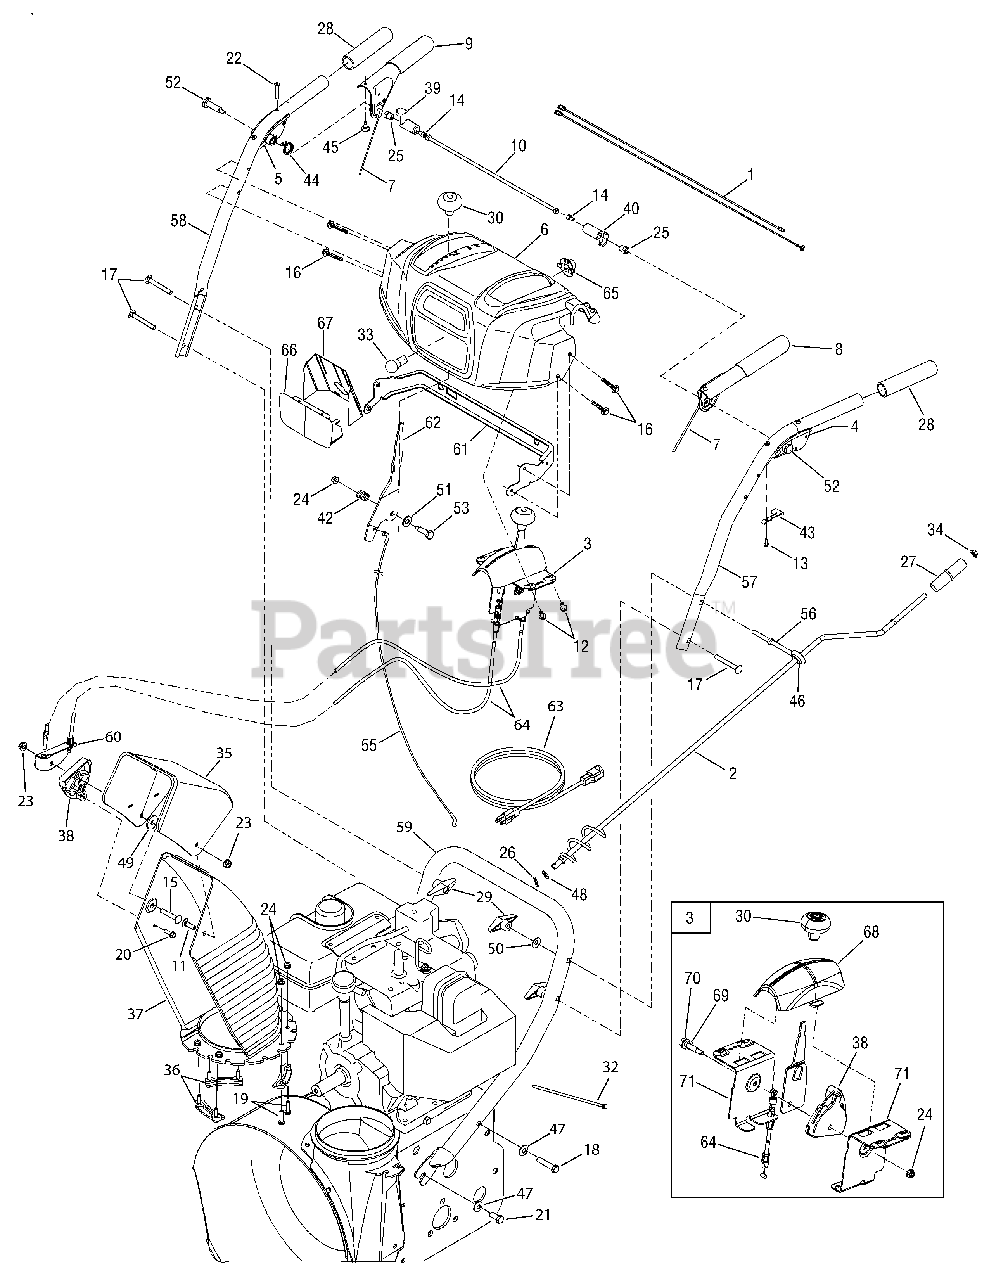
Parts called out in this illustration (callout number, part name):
1	Wire Harness
3	2-Way Chute Control (TM) Assy
4	Handle Clutch Lock - LH
5	Handle Clutch Lock - RH
6	Handle Panel
7	Cable Assembly, Auger/Drive
8	Handle Engage Assy - LH
9	Handle Engage Assy - RH
10	Rod Ass’y, Clutch Lock Pivot
11	Screw, Carriage, 5/16-18 x 1.0
12	Hi-Lo Screw, 1/4-15 x 0.5
13	Screw, #8-16 x 0.50
14	Screw, 1/4-20 x.375
15	Bolt, Carriage, 5/16-18 x 1.75
16	Screw, 1/4-20 x 1.625
17	Screw, Carriage, 5/16-18 x 2.5
18	Screw, Hex, 3/8-16 x 2.00 Lock, Gr5
19	Screw, 1/4-20 x 1.00
20	Hi-Lo Screw, 1/4-15 x .75
21	Screw, Hex, 3/8-16 x 1.0 Lock, Gr5
22	Screw, #10-24 x 0.375
23	Flange Lock Nut, 5/16-18
24	Flange Lock Nut, 1/4-20
25	Shoulder Nut, 1/4-20
26	Pin, Internal Cotter Pin
27	Knob, Crank
28	Handle Grip
29	Knob, Wing Nut, 5/16-18
30	Shift Knob
32	Cable Tie
33	Lamp
34	Cap, Push, 3/8
35	Upper Chute
36	Chute, Flange Keeper
37	Lower Chute
38	Chute Tilt Cable Guide
39	Lock Plate
40	Clutch Lock Cam
42	Compression Spring
43	Clutch Lock Spring
44	Torsion Spring
45	Rubber Bumper
46	Grommet, Rubber
47	Washer, Bel, .375 x .87 x .063
48	Washer, .375 x .738 x .063
49	Flat Washer
50	Washer, Belleville, .34 x .872 x .06
51	Flat Washer
52	Shoulder Screw, 1/4-20 x 1.345
53	Shoulder Screw
55	Speed Selector Cable
63	Extension Cord, 110V
64	Cable, Chute Tilt
65	Light Socket
67	Reflector Label
68	Cover, Tilt Cover
69	Washer, Spring, .39 x .625 x .012
70	Screw, Shoulder, .31 x .995:1/4-20
